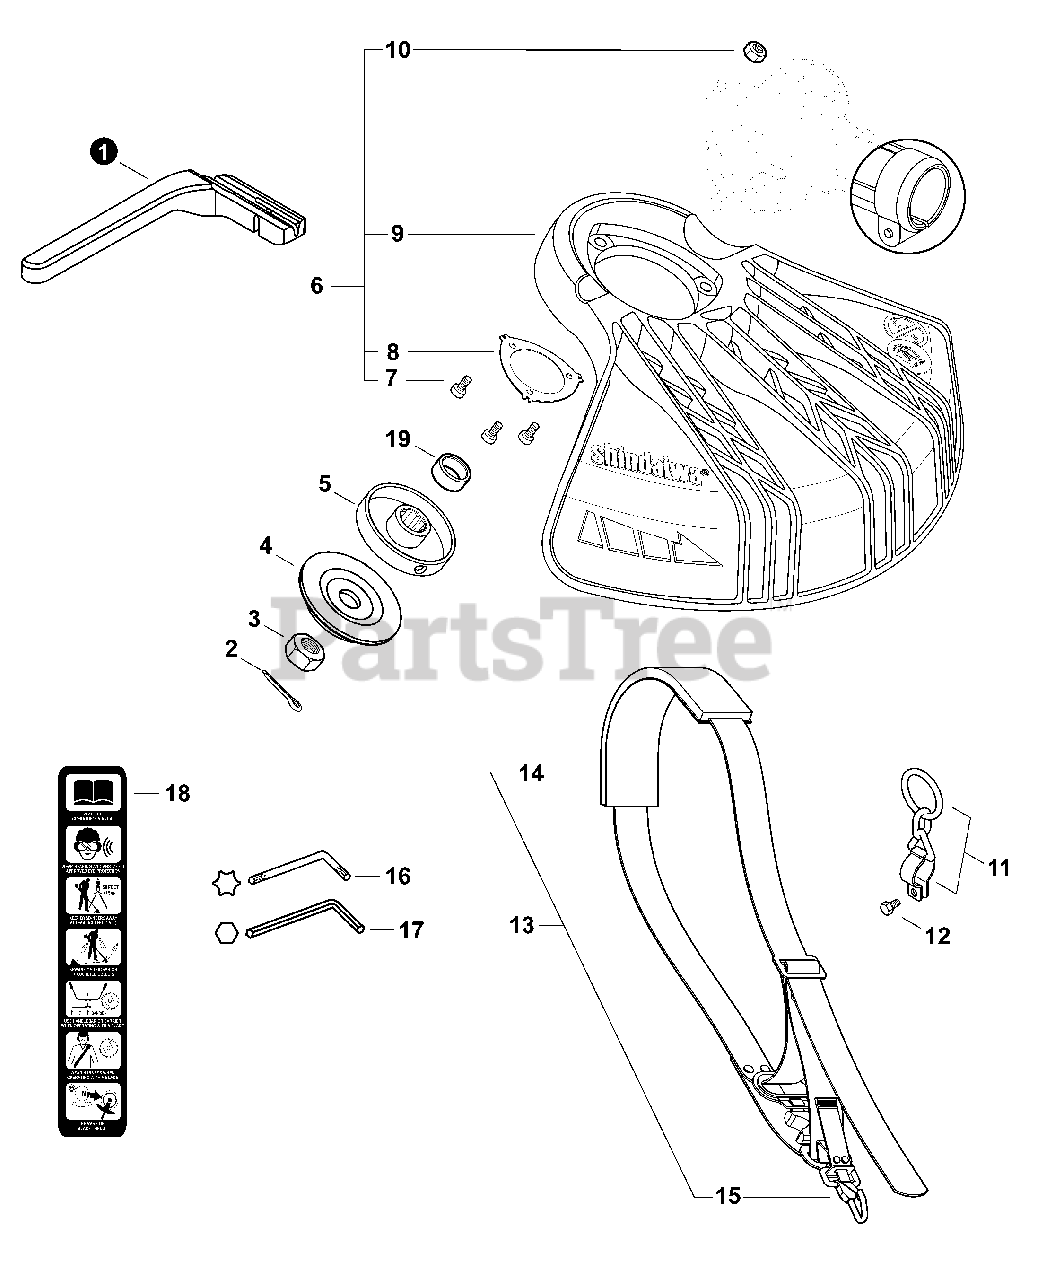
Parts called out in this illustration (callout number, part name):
1	BAR, BARRIER
2	PIN, COTTER 2x22
3	NUT 10x1.25 LH
4	PLATE, ADAPTOR - LOWER
5	PLATE, ADAPTOR - UPPER
6	DEBRIS SHIELD KIT - BLADE
7	BOLT, TORX 5x25
8	PLATE, SHIELD
9	SHIELD, DEBRIS - BLADE
10	NUT, LOCK M5
11	HANGER SET, HARNESS
12	BOLT, TORX 5x12
13	HARNESS ASSY, SHOULDER
14	PAD, SHOULDER
15	HOOK, SNAP
16	WRENCH, T27 80x30
17	WRENCH, ALLEN 4 MM
18	LABEL - CAUTION (BLADE CAPABLE)
19	SPACER 11.8x15x9
